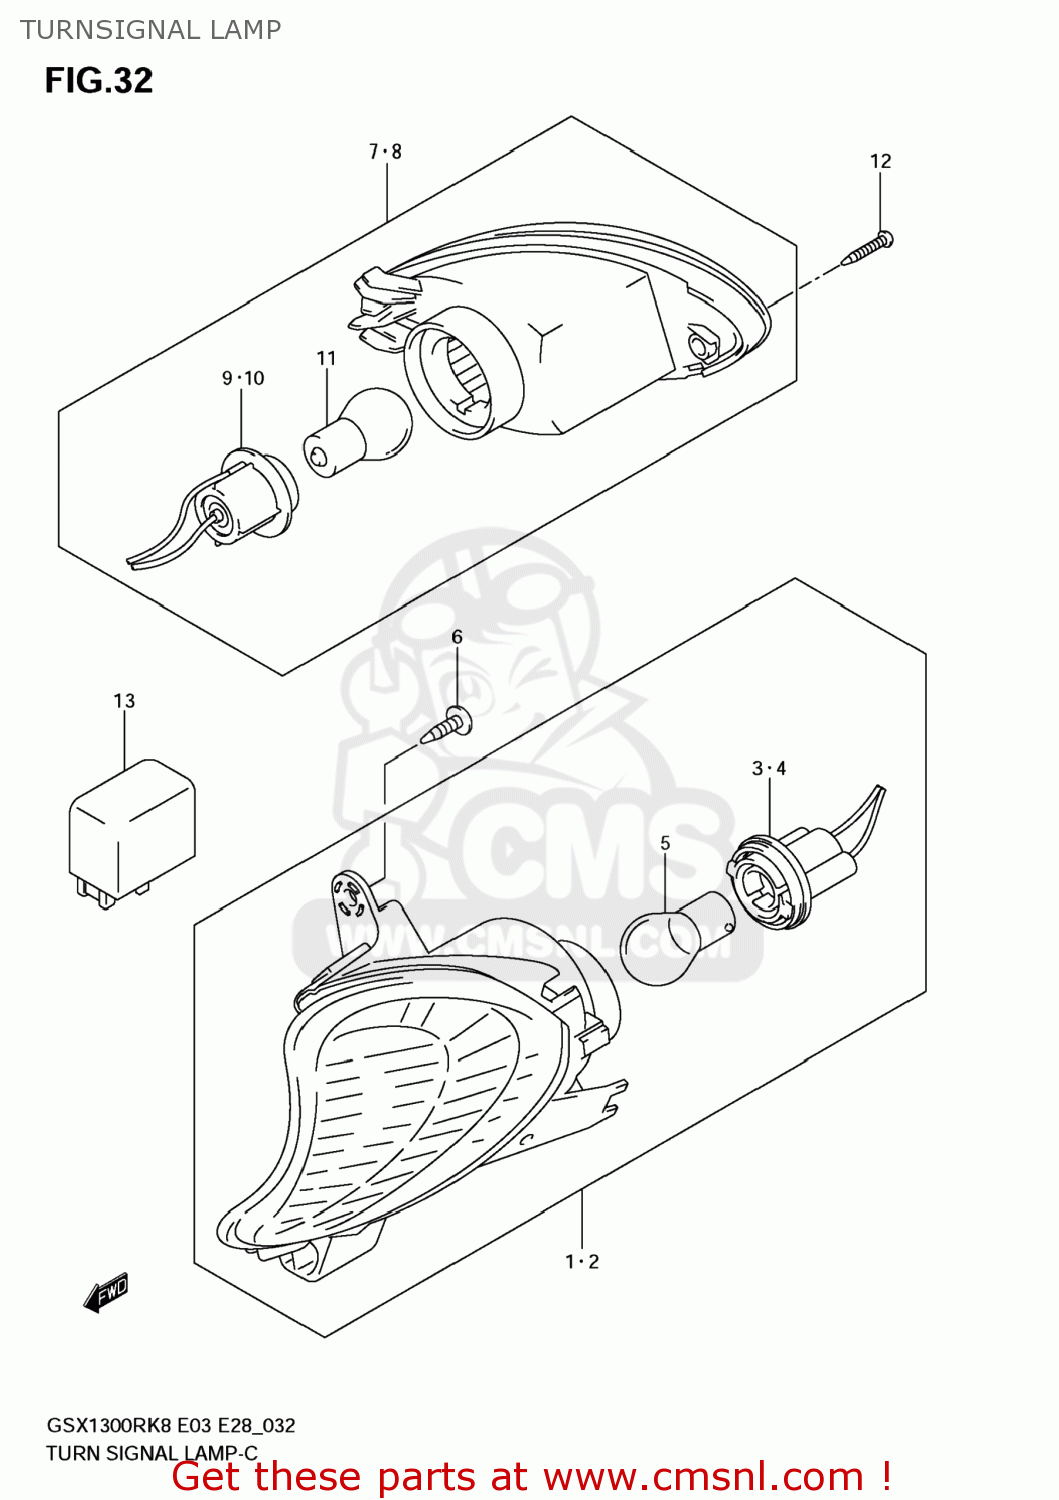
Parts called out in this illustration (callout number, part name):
1	LAMP ASSY,FRON
2	LAMP ASSY,FRON
3	SOCKET & CORD,R
4	SOCKET & CORD,L
5	BULB(12V21W,AMBER)
6	SCREW
7	LAMP ASSY,REAR
8	LAMP ASSY,REAR
9	SOCKET & CORD,R
10	SOCKET & CORD,L
11	BULB(12V21W,AMBER)
12	SCREW(4X20)
13	RELAY ASSY,TURNSIGNAL LAMP
